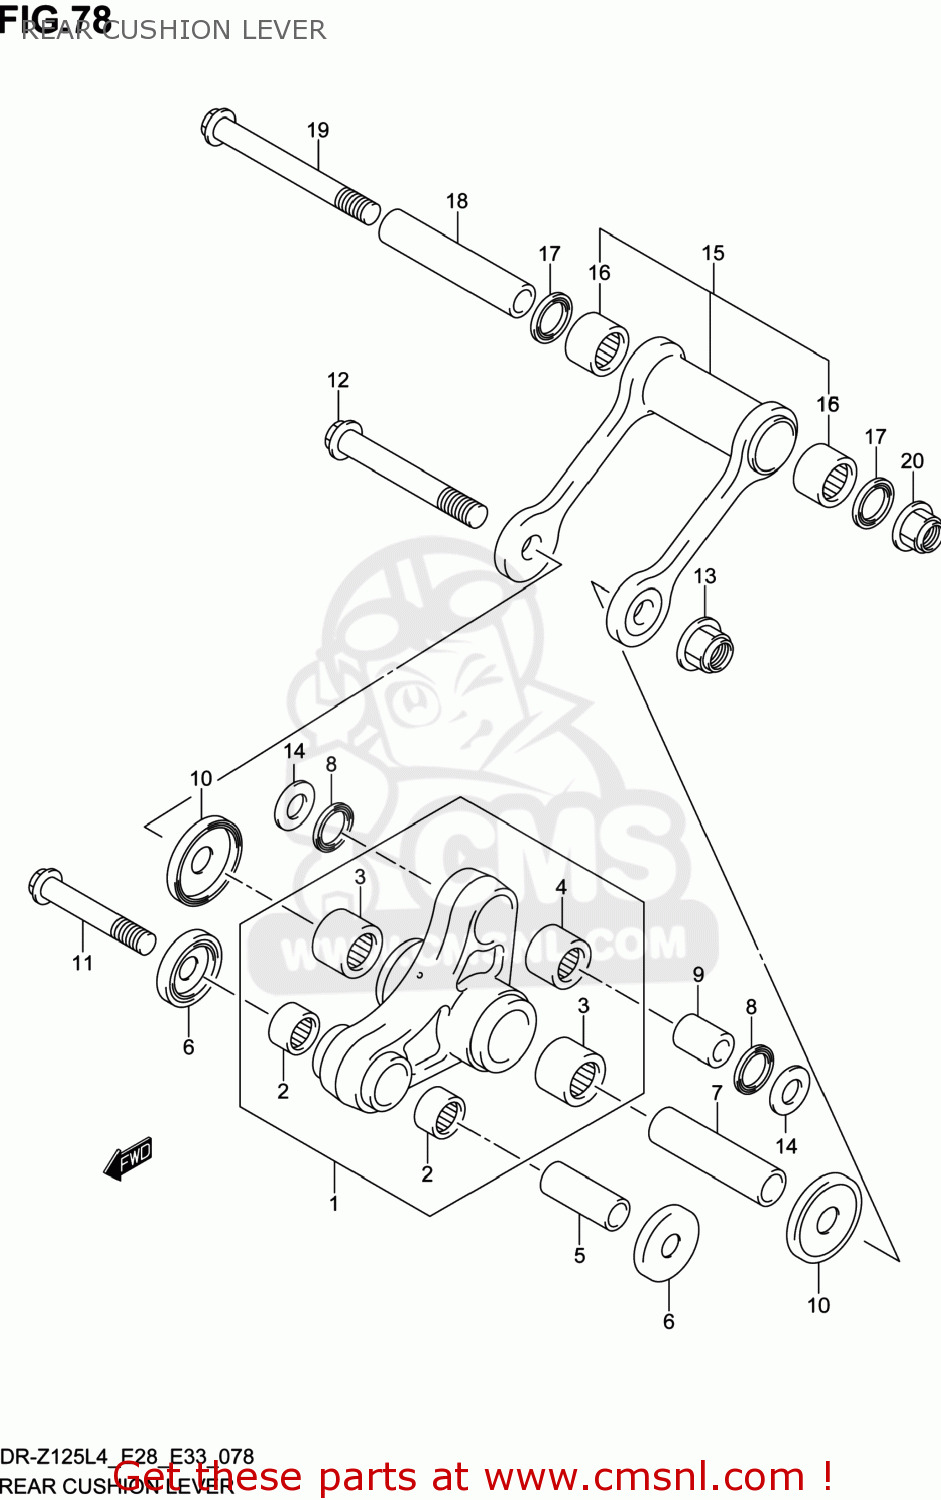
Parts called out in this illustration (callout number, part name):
1	LEVER SET,RR CUSHION
2	BEARING(14X20X12)
3	BEARING(17X24X20)
4	BEARING(16X22X12)
5	SPACER,RR CUSHION LEVER FR
6	SEAL,RR CUSHION LEVER FR DUST
7	SPACER(12X17X60)
8	SEAL,OIL(16X22X2.5)
9	SPACER,RR CUSHION LEVER RR
10	SEAL,RR CUSHION LEVER FR DUST
11	BOLT,RR CUSHION LEVER FR
12	BOLT,RR CUSHION LEVER CTR
13	NUT
14	WASHER,THRUST LVR CUSHION RR
15	ROD SET,RR CUSHION
16	BEARING(17X24X20)
17	SEAL,OIL(17X24X3)
18	SPACER,RR CUSHION ROD
19	BOLT,RR CUSHION ROD
20	NUT
